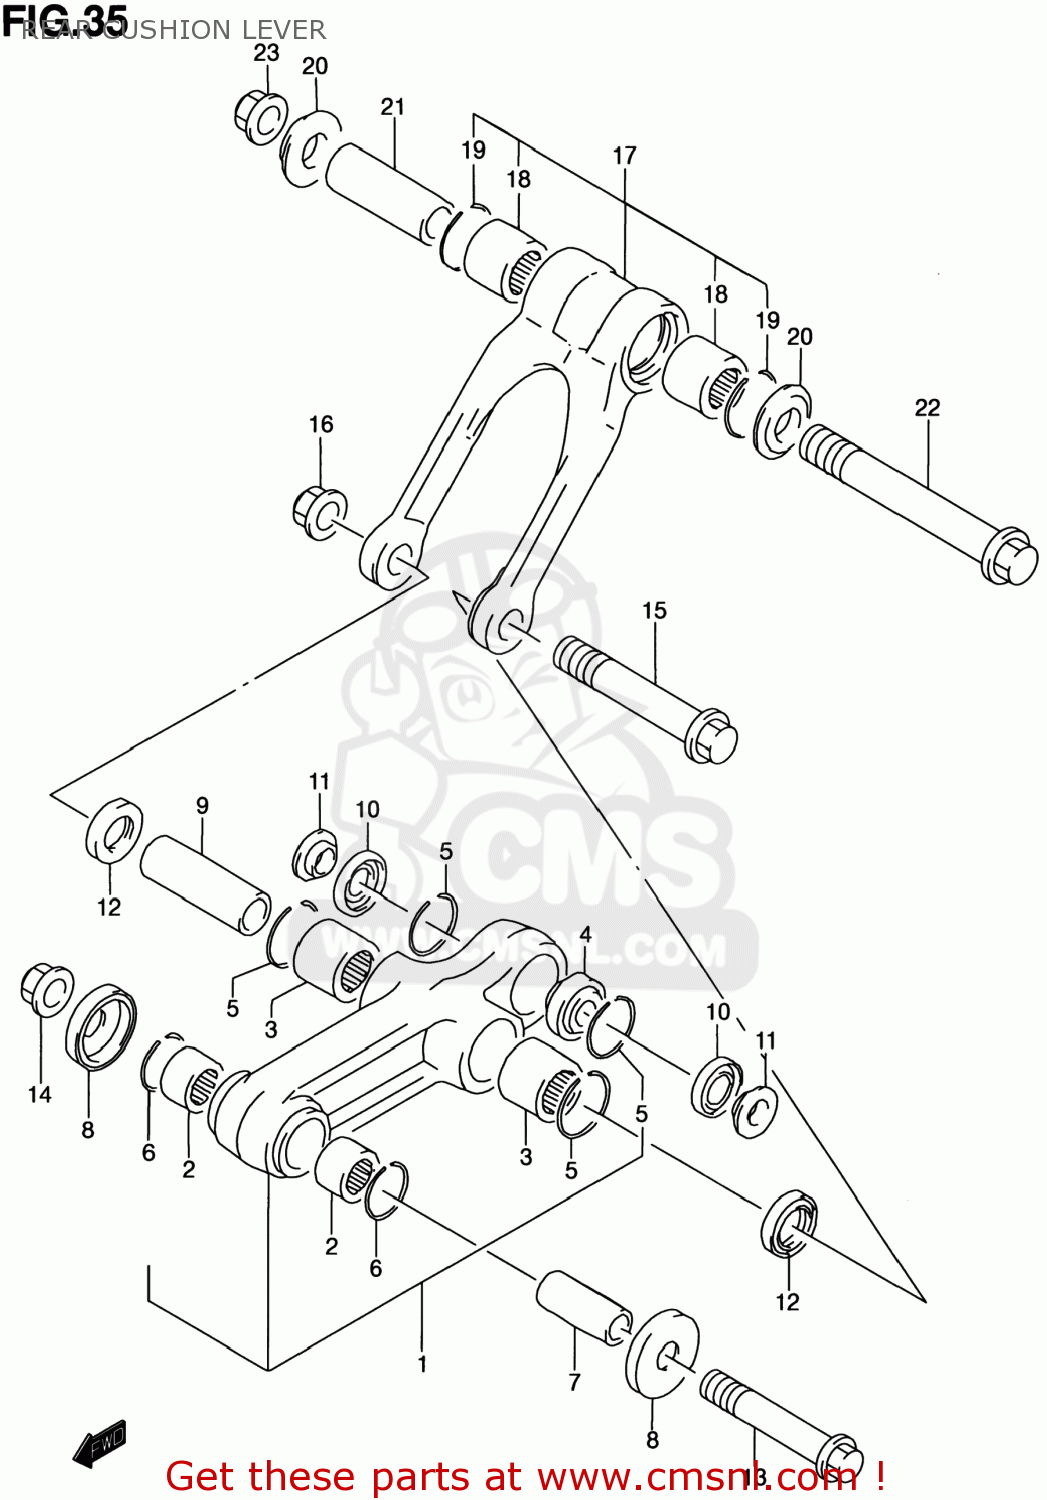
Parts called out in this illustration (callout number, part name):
1	LEVER SET,RR CUSHION
2	BEARING(14X20X12)
3	BEARING(17X24X20)
4	BEARING,RR CUSHION LEVER
5	RING,STOPPER
6	CIRCLIP,PISTON PIN
7	SPACER,RR CUSHION LEVER FR
8	SEAL,RR CUSHION LEVER FR DUST
9	SPACER,RR CUSHION LEVER CTR
10	SEAL,RR CUSHION LEVER RR DUST
11	SPACER,RR CUSHION LEVER RR
12	SEAL,OIL(17X24X3)
13	BOLT,RR CUSHION LEVER FR
14	NUT
15	BOLT,RR CUSHION LEVER CTR
16	NUT 12MM
17	ROD SET,REAR CUSHION,LEFT
18	BEARING(17X24X20)
19	RING,STOPPER
20	SPACER,RR CUSHION ROD SIDE
21	SPACER,RR CUSHION ROD
22	BOLT,RR CUSHION ROD
23	NUT 12MM
